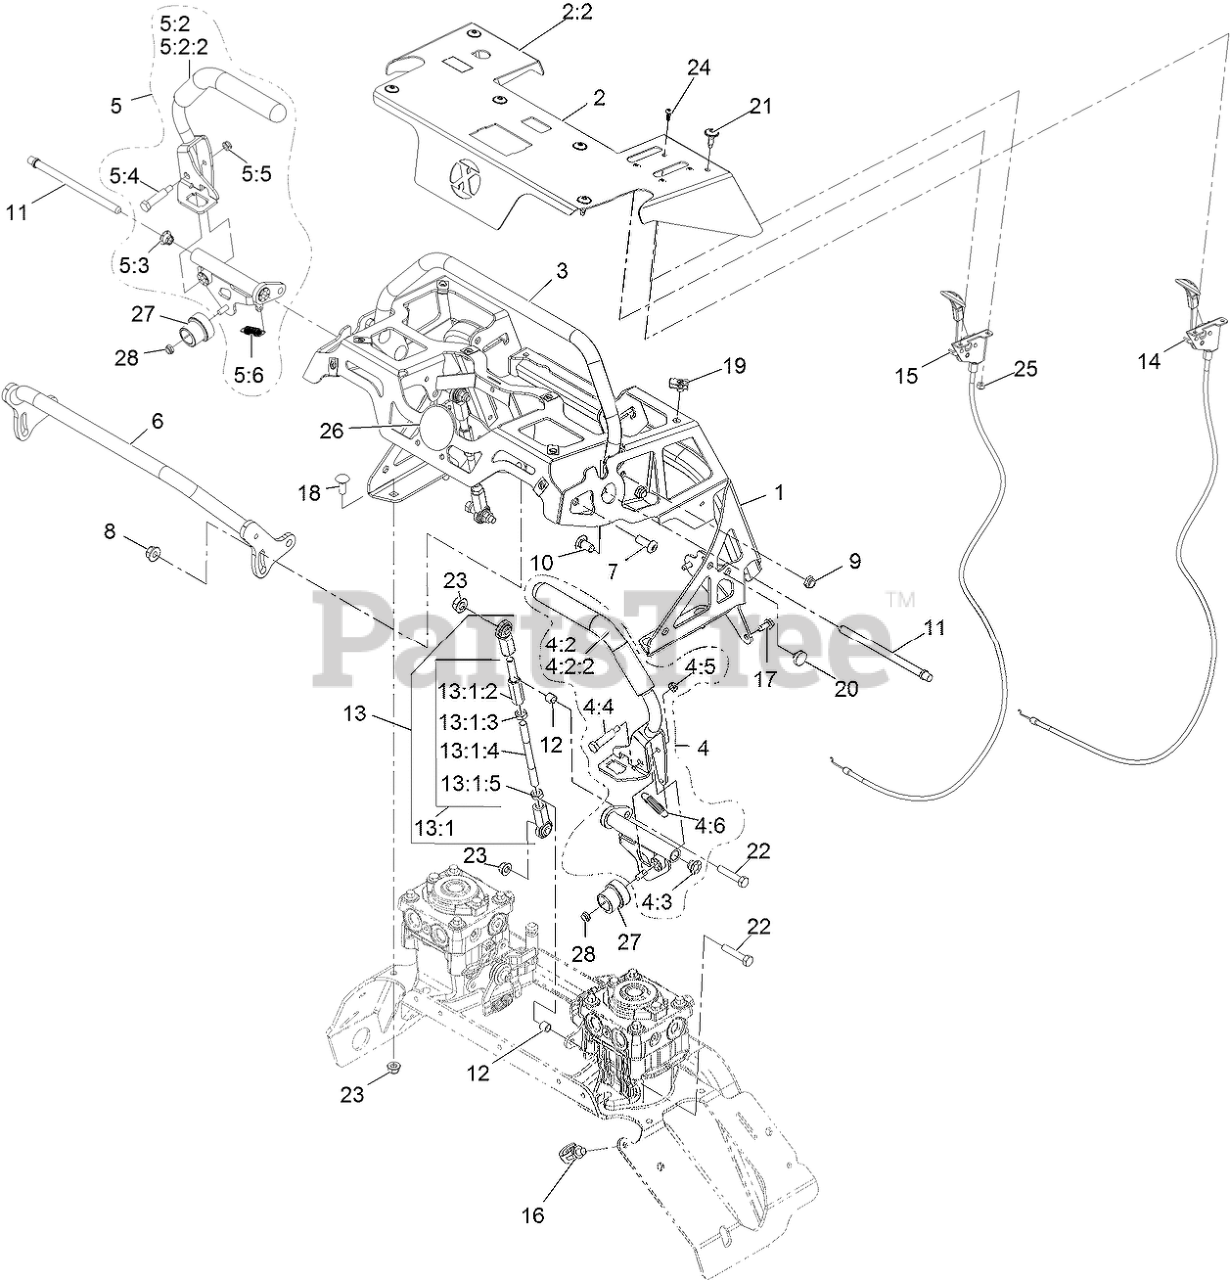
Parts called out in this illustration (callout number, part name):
1	ASM, Control Tower W/Decal
2	ASM, Control Panel W/ Decals
2:2	Decal-Control Panel Non-EFI
3	Weld, Rear Ref Bar
4	ASM, Motion Control, Lt
4:2	ASM, Lt Control Lever W/ Grip
4:2:2	Grip, Drive Lever
4:3	Bearing, Igus
4:4	BOLT-SHOULDER
4:5	NUT-LOCK, NI
4:6	SPRING-EXTENSION
5	ASM, Motion Control, Rt
5:2	ASM, Rt Control Lever W/ Grip
5:2:2	Grip, Drive Lever
5:3	Bearing, Igus
5:4	BOLT-SHOULDER
5:5	NUT-LOCK, NI
5:6	SPRING-EXTENSION
6	Weld, Front Ref Bar
7	SCREW-HSBH
8	NUT-HF, NI
10	SCREW-CARR
11	PIN, PIVOT
13	ASM, Linkage
13:1	ASM, Motion Control Link
13:1:2	ROD-ADJUSTMENT
13:1:3	NUT-HEX JAM, LH
13:1:4	Link, Motion Control
13:1:5	NUT-HJ
14	CONTROL, CHOKE
15	CONTROL, THROTTLE
16	CLIP-TIE
17	SCREW-HWH
18	SCREW-CARR
21	Screw, Torx
22	SCREW-HH
23	NUT-HF, NI
24	SCREW, BHCS
25	NUT-LOCK, NI
26	Decal-Cover
28	NUT-LOCK, NI
